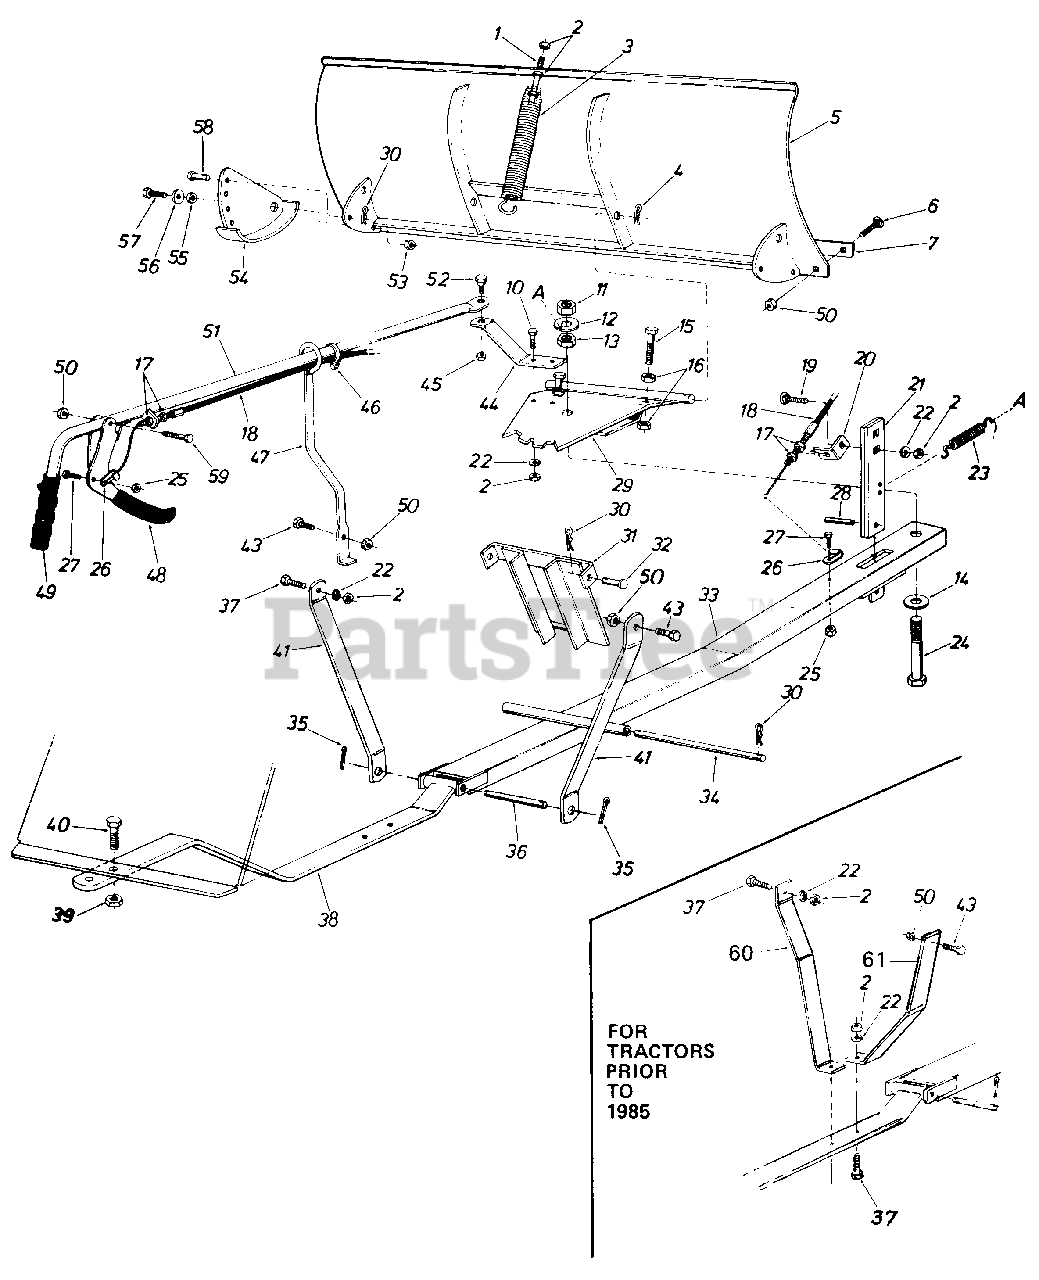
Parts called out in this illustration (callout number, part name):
1	Hex Scr. 3/8-16 x 4.50" Lg.
2	Hex Nut 3/8-16 Thd.
3	Blade Adjustment Spring
4	Hair Pin Cotter 5/32" Dia.
5	48" Blade Ass'y.
6	Carriage Bolt 5/16-18 x.75" Lg.
7	Wear Plate 48"
10	Hex Scr. 3/8-16 x 1.00" Lg.
11	Hex L.-Nut 3/4-10 Thd.
12	Fl.-Wash..810" I.D. x 2.00" O.D.
13	Hex Jam Nut 3/4-10 Thd .
14	Fl.-Wash. .810" I.D. x 2.00" O.D.
15	Hex Scr. 1/2-13 x 2.00" Lg.
16	Hex Nut 1/2-13 Thd.
17	Hex Jam Nut 5/16-24 Thd.
18	Control Cable Ass'y.
19	Carriage Bolt 3/8-16 x 1.25" Lg.
20	Cable Guide Bracket
21	Angle-Lock Bar
22	L.-Wash. 3/8" Scr.
23	Angle Lock Spring
24	Hex Scr. 3/4-10 x 4.00" Lg.
25	Hex L.-Nut 1/4-20 Thd.
26	Clevis Lanyard Fitting
27	Hex Scr. 1/4-20 x .75" Lg.
28	Spring Pin Spirol 1/4" Dia. x 1.00" Lg.
29	Pivot Plate Ass'y.
30	Hair Pin Cotter 3/32" Dia.
31	Guide Bracket Ass'y.
32	Clevis Pin 1/2" Dia. x 1.00" Lg.
33	Push Bar Ass'y.
34	Lift Shaft
35	Cotter Pin 5/32" Dia. x 1.00" Lg.
36	Pivot Pin
37	Hex Scr. 3/8-16 x 1.25" Lg.
38	Hanger Bracket Ass'y.
39	Hex L.-Nut 5/8-11 Thd.
40	Hex Scr. 5/8-11 x 1.50" Lg.
41	Hanger Link
43	Hex 5/16-18 x 1.00" Lg.
44	Blade Pivot Bracket
45	Hex L.-Nut 3/8-16 Thd.
46	Nylon Cable Tie
47	Tube Guide Ass'y.
48	Clutch Grip Ass'y.
49	Grip-3/4" Handle
50	Hex L-Nut 5/16-18 Thd.
51	Tube Handle Ass'y.
52	Shld. Scr.-Special 3/8-16 Thd.
53	Hex L.-Nut 3/8-16 Thd.
54	Skid Assembly
55	Spacer
56	Fl.-Wash. .385" I.D. x 1.00" O.D.
57	Hex Scr. 3/8-16 x .75" Lg.
58	Clevis Pin 5/16" Dia. x .75" Lg.
59	Hex Scr. 5/16-18 x 1.50" Lg.
60	Mounting Brkt.-L.H.
61	Mounting Brkt.-R.H.
